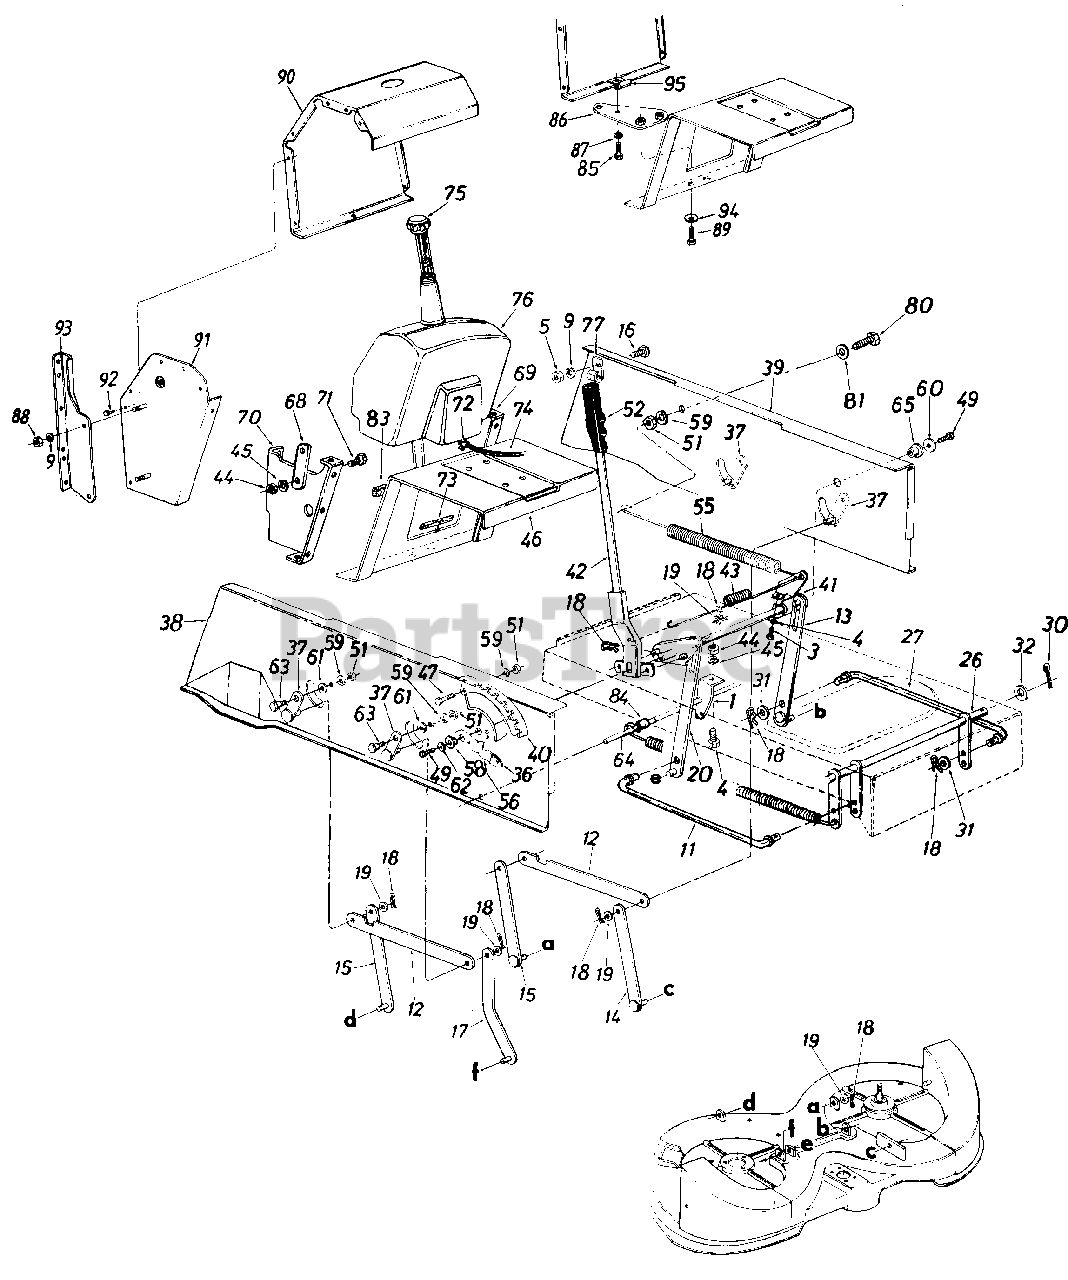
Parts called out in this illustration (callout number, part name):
1	Spring Hanger Bracket
3	Hex Jam Nut 5/16-18 Thd.
4	Hex Bolt 1/4-20 x .62" Lg.
5	Hex Nut 5/16-18 Thd.
9	L-Wash. 5/16" I.D.
11	Stabilizer Rod
12	Connecting Rod
13	Deck Lift Link Ass'y.
14	Deck Hanger Link Ass'y.-Rear L.H.
15	Deck Hanger Link Ass'y.
16	Hex Bolt 5/16-18 x .75" Lg.
17	Deck Hanger Link Ass'y.
18	Inter. Cotter Pin 1/2" Dia.
19	Fl-Wash. .531 I.D. x .93" O.D.
20	Deck Lift Link Ass'y.
26	Stabilizer Shaft Ass'y.
27	Stabilizer Rod
30	Cotter Pin 1/8" Dia. x 1.25"
31	Fl-Wash. .385" I.D. x .620"
32	Fl-Wash. .635" I.D. x 1.12' O.D.
36	Knob-Height Adj.
37	Pivot Link Ass'y.
38	Side Panel Upper Frame-R.H.
39	Side Panel Upper Frame-L.H.
40	Index Brkt.
41	Lift Shaft Ass'y.
42	Lift Handle Brkt. Ass'y.
43	Ext. Spring .56" I.D. x 32 Coils
44	Hex Nut 1/4-20 Thd.
45	L-Wash. 1/4" I.D.*
46	Hitch Plate
47	Hex Bolt 5/16-18 x .75" Lg.
49	Hex Wash. TT-Tap Scr. 5/16-18 x .62" Lg.
51	Hex Nut 5/16-18 Thd.
52	Grip
55	Ext. Spring 11" Lg.
56	Deck Lift-Down Stop
58	Flange Brg. .630" I.D.
59	L-Wash. 5/16" I.D.
61	Fl-Wash. .344" I.D. x .62" O.D. x .063
62	Fl-Wash. .344" I.D. x 1.125" O.D.
63	Shld. Bolt .437" Dia. x .180
64	Running Board Rod
65	Flange Brg. .632" I.D.
68	Fender Support Brkt.
69	Grass Catcher Support Brkt. -L.H.
70	Grass Catcher Support Brkt. -R.H.
71	Hex Bolt 1/4-20 x .50" Lg.
72	Hose Clamp-406n Dia.
73	Trim Strip-5" Lg.
74	Gas Line-44" Lg.
75	Gas Tank Cap
76	Gas Tank
77	Hose Clamp
80	Hex Bolt 5/16-18 x 1.50" Lg.
81	Fl-Wash. .344" I.D. x 375n O.D.
83	Foam Strip 3/8" x 1-1/8" x 11/2" Lg.
84	Spacer .523" I.D. x 640n O.D. x 1.95" Lg.
85	Hex Bolt 5/16-18 x ln Lg.-Gr. 5
86	Hitch Bar
87	L-Wash. 5/16" I.D.
88	Hex Nut 5/16-18 Thd
89	Self-Tap Scr. 3/4" Lg.
90	Gas Tank Housing
91	Side Panel-R.H.
93	Mounting Bracket-R.H.
94	Bell-Wash. 3/8" I.D.
95	Speed Nut
